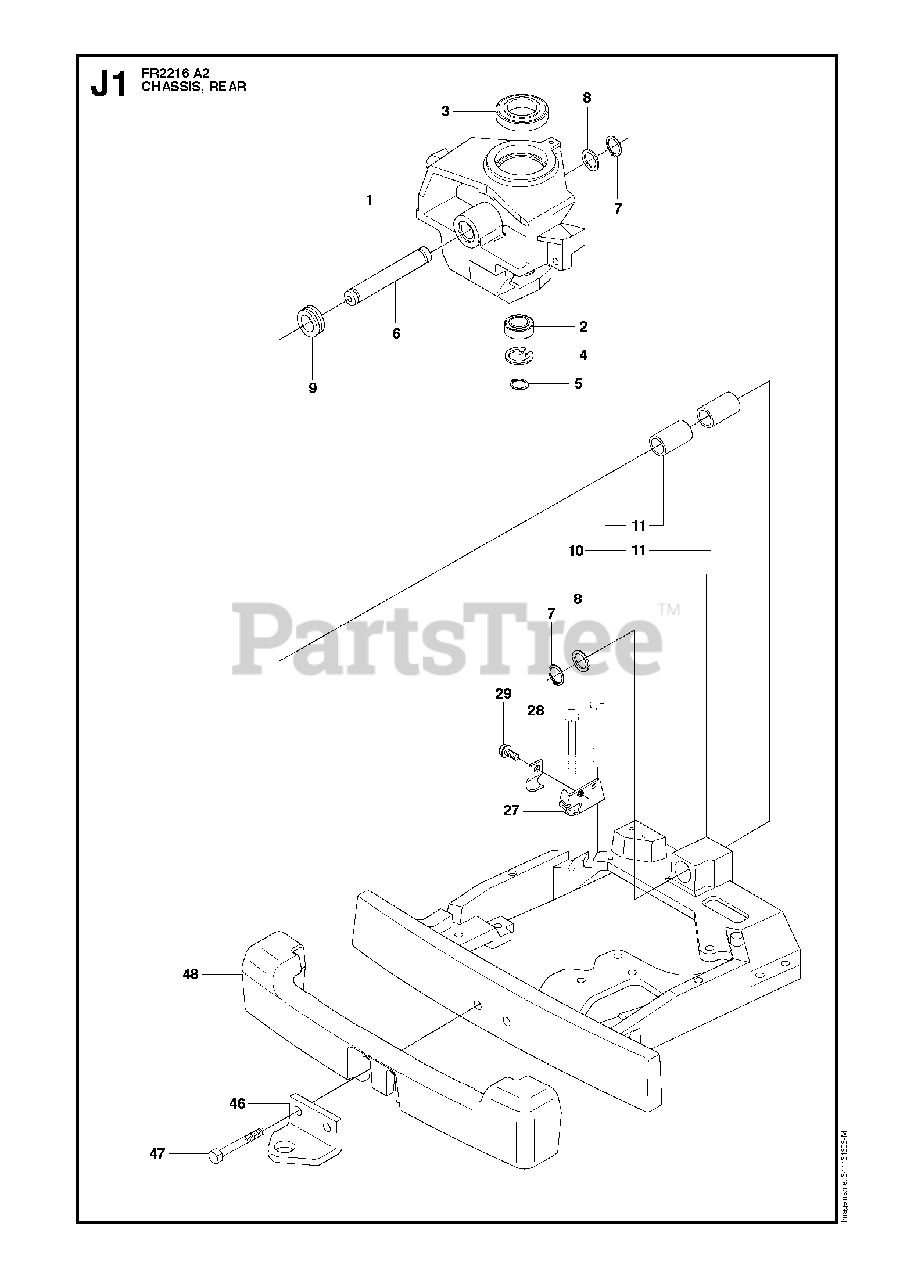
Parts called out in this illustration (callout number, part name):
2	BALL BEARING 6005-2RS
3	BALL BEARING 6010 2RS1
4	CIRCLIP SGH 47
5	RETAINING RING SGA 25
7	RETAINING RING SGA 25
11	BUSHING
12	HYDROSTAT
15	WASHER BRB 8.4X17
16	NUT
20	CONNECTOR
21	NUT
23	WASHER
24	SCREW 8X20
26	LOCKNUT M5
31	SPRING
32	TENSIONER
33	TENSIONER
34	PULLEY
35	SCREW
36	SPACER
37	LOCKNUT M8
38	WASHER
39	SCREW 8X20
46	DRAW RING
